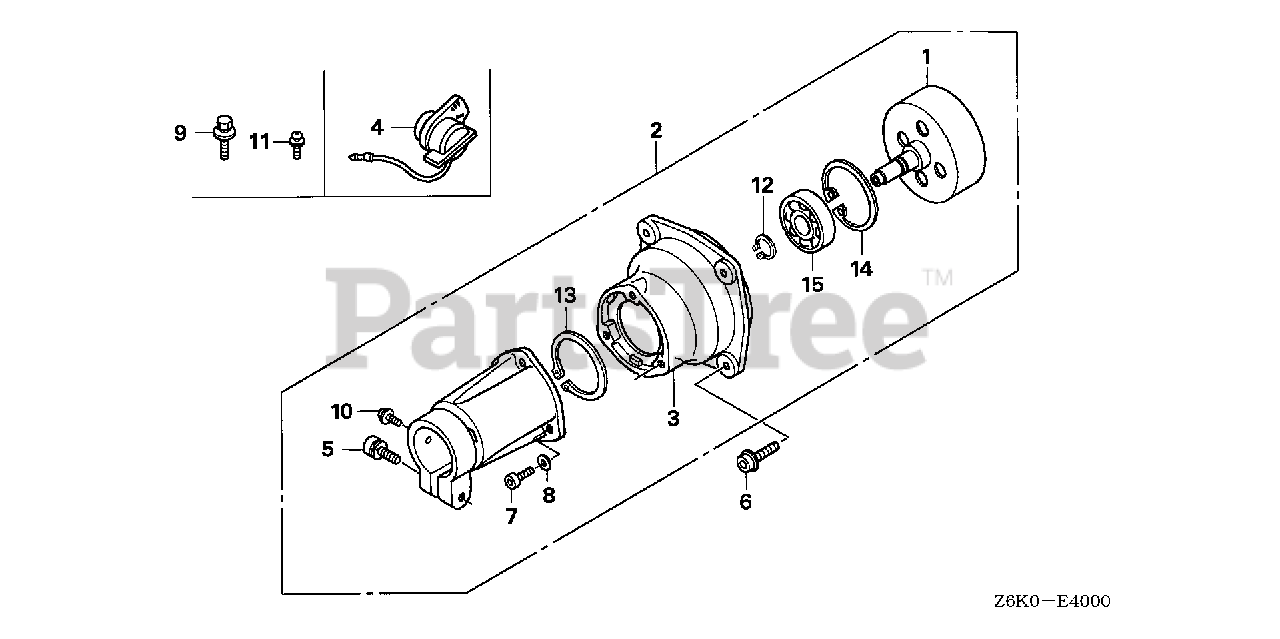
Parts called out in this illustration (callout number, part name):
1	CLUTCH OUTER
2	HOUSING ASSY., CLUTCH
3	HOUSING A, CLUTCH
4	SWITCH ASSY., ENGINE STOP (TOYO DENSO)
5	BOLT, SOCKET (6X20)
6	BOLT, FLANGE SOCKET (6X20)
7	BOLT, SOCKET (5X20)
8	WASHER (5MM)
9	BOLT-WASHER (6X28)
10	SCREW-WASHER (5X10)
11	SCREW-WASHER (5X10)
12	CIRCLIP (OUTER) (15MM)
13	CIRCLIP (OUTER) (30MM)
14	CIRCLIP (INNER) (35MM)
15	BEARING, RADIAL BALL (6202)
